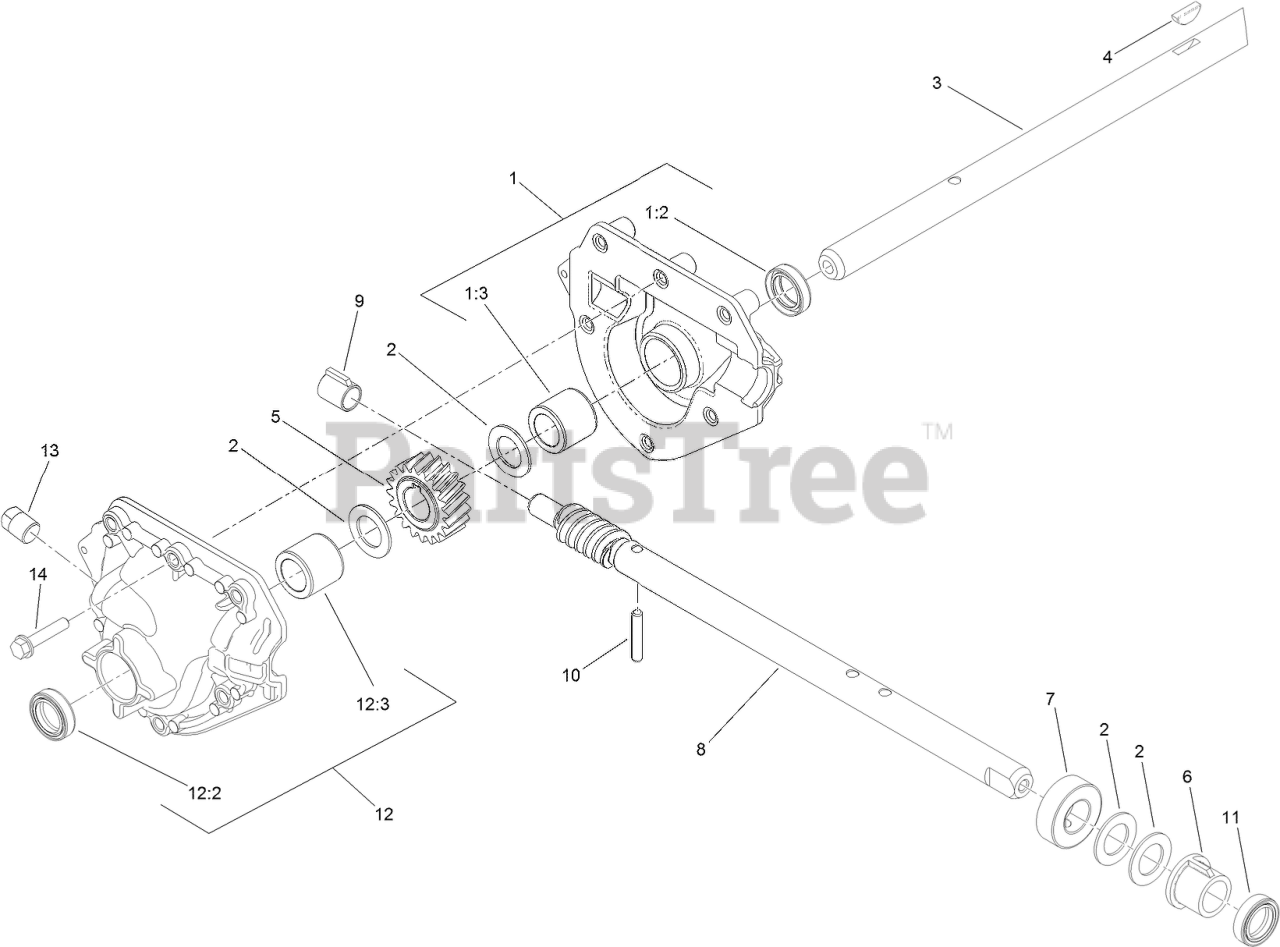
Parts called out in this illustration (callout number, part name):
1	RH AUGER GEARCASE ASM
1:2	SEAL-SHAFT
1:3	BUSHING-SLEEVE
2	WASHER-THRUST
3	SHAFT-OUTPUT, AUGER
4	KEY-WOODRUFF
5	GEAR-HELICAL, 20 TOOTH
6	BUSHING-INPUT
7	COLLAR-THRUST
8	SHAFT-IMPELLER, ROLLED
9	BUSHING-WORM
10	PIN-DOWEL
11	SEAL-SHAFT
12	LH AUGER GEARCASE ASM
12:2	SEAL-SHAFT
12:3	BUSHING-SLEEVE
13	PLUG-PIPE, SQH
14	SCREW-HWHTF
